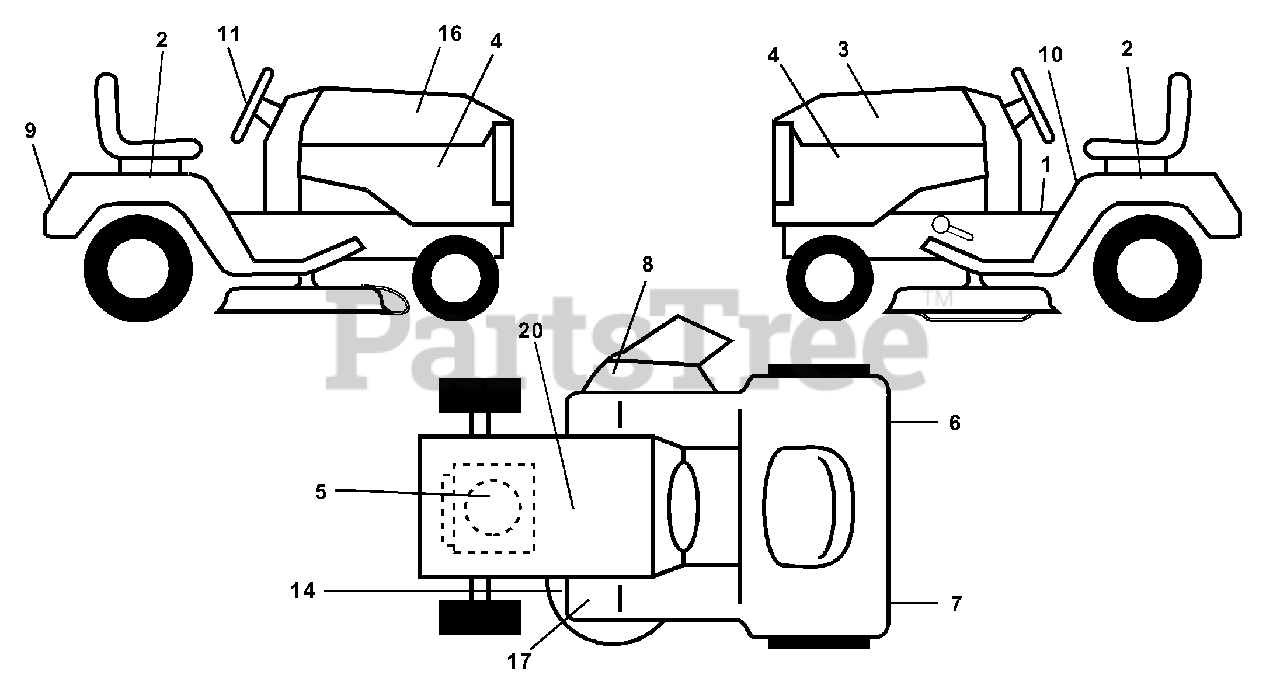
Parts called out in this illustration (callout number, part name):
1	Decal Dash
2	Decal Fender Auto
3	Decal Hood LH
4	Decal Side Panel
5	Decal HP Engine
6	Decal Reflector Rh
7	Decal Reflector Lh
8	Decal Warning Mower
9	Decal Fender Logo
10	Decal Fender Danger E/F
11	Decal Ins Strg Whl
14	Decal V-Belt Schematic
16	Decal Hood Rh
17	Decal Clutch
20	Decal Bat Dan/Psn
